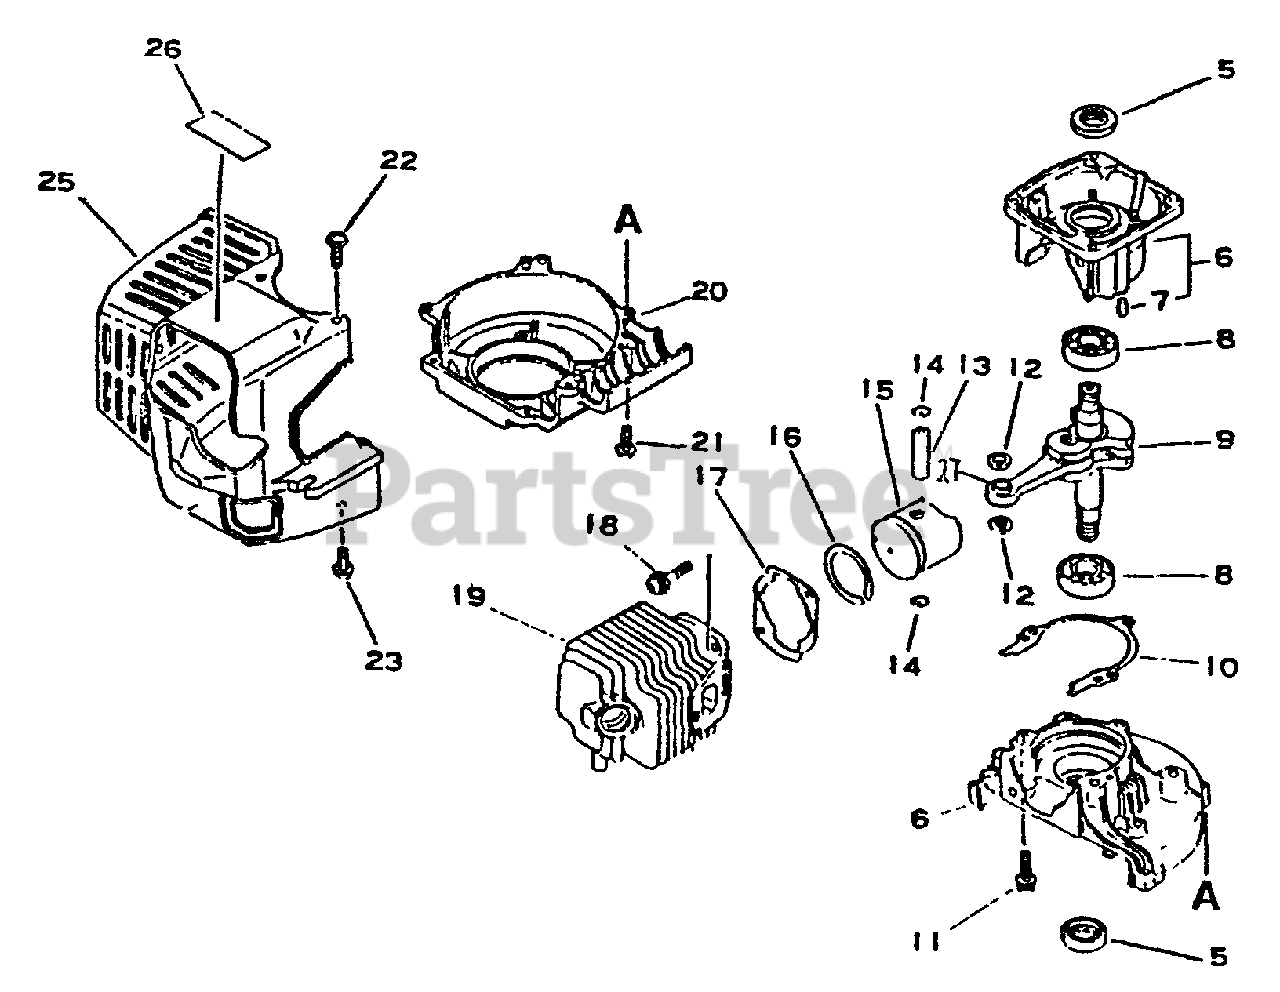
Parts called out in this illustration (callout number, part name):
5	SEAL, OIL
6	CRANKCASE KIT
7	PIN - LOCATING
8	BEARING, BALL - 6201
9	CRANKSHAFT ASSY
10	GASKET, CRANKCASE
11	SCREW - 5X28
12	SPACER, PISTON
13	PIN, PISTON
14	RING, RETAINING
15	PISTON
16	RING, PISTON
17	GASKET, CYLINDER
18	SCREW - 5X22
19	CYLINDER
20	CASE, FAN
21	SCREW - 4X14
22	SCREW - 4X12
23	SCREW - 4X16
25	COVER, ENGINE - ORANGE
26	LABEL - MODEL HC-1001
27	BEARING, NEEDLE
